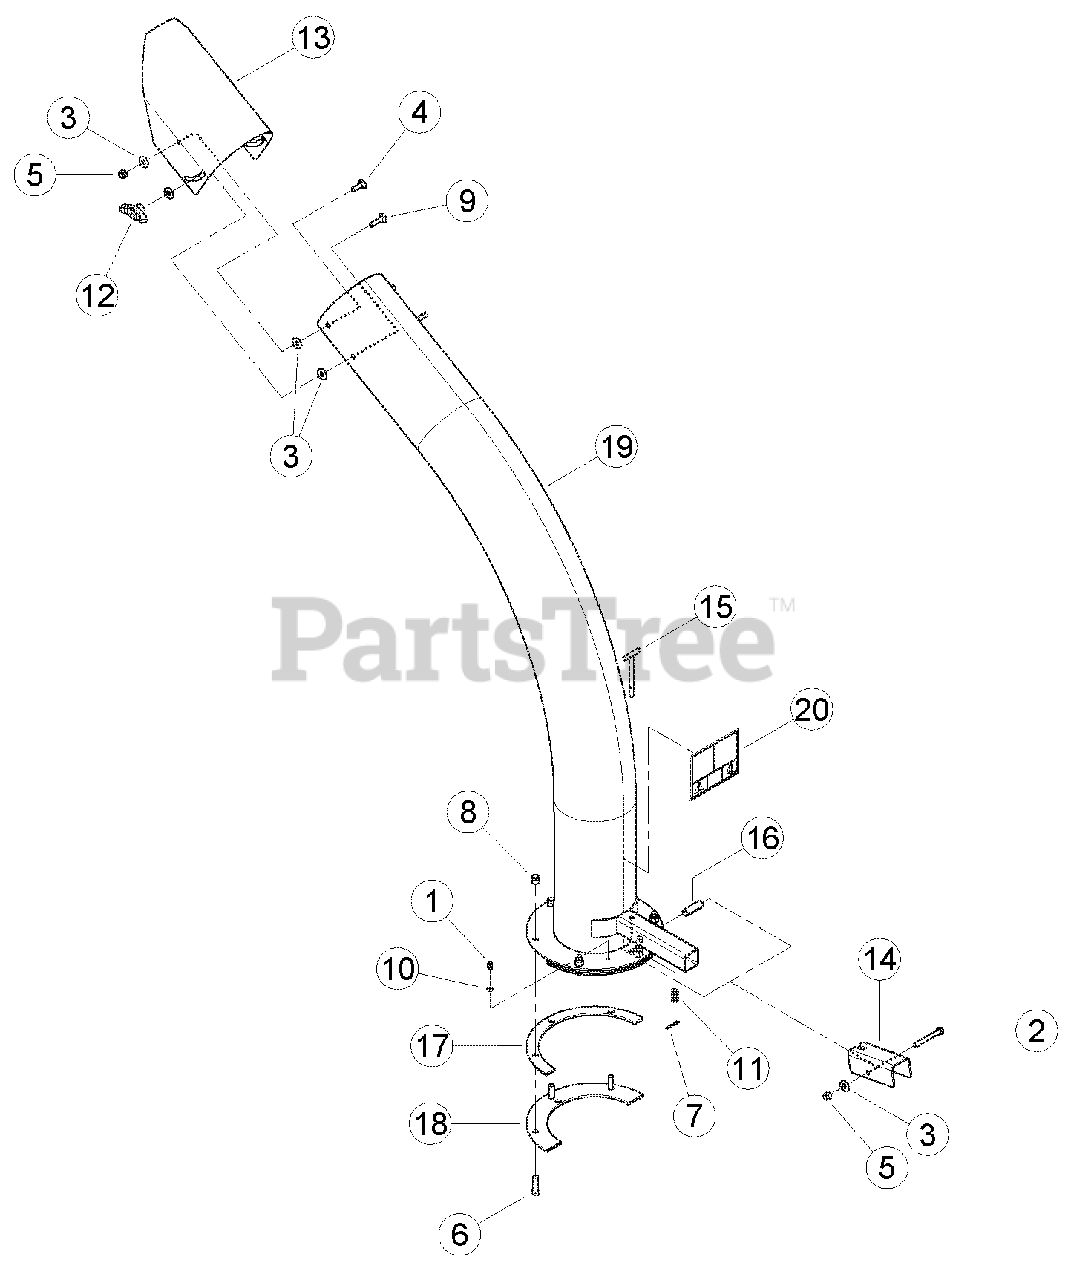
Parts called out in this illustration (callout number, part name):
1	FITTING, 1/4 SELF-TAP GREASE
2	BOLT, 5/16 X 2-1/2 HEX HD GR5 ZP
3	WASHER, 5/16 FLAT ZP
4	BOLT, 5/16 X 1 CRG GR5 ZP
5	NUT, 5/16 NE NYLOCK ZP
6	BOLT, 3/8 X 1-1/4 HEX HD GR5 ZP
7	PIN, 1/8 X 1.00 COTTER ZP
8	NUT, 3/8 NE NYLOCK ZP
9	BOLT, 5/16 X 1-1/4 CRG GR5 ZP
10	WASHER, .254 X .400 X .048 FLAT
11	SPRING, LOCK COMPRESSION
12	KNOB, 5/16-18 UNC TEE W/LOCKING INSERT
13	DEFLECTOR, BLOWER-VAC DISCHARGE
14	LEVER, DISCHARGE LOCK
15	WELDMENT, DISCHARGE LOCK PIN
16	TUBE, DISCHARGE LOCK PIVOT
17	SPACER, DISCHARGE PIVOT
18	RING, DISCHARGE CLAMP
19	ASSEMBLY, 6 INCH DISCHARGE, SERVICE PART
20	DECAL, DISCHARGE DEBRIS & LOCK
